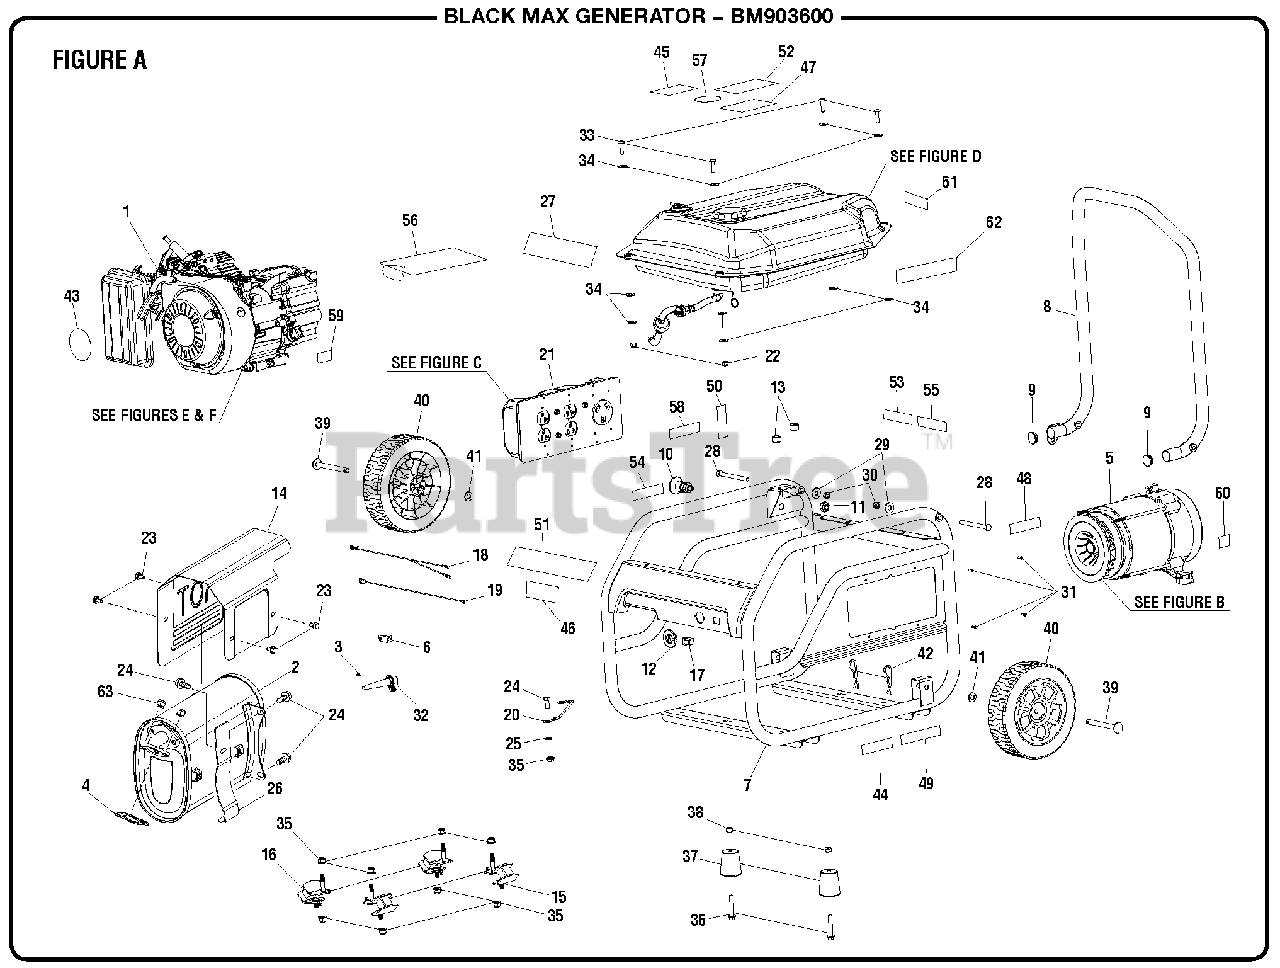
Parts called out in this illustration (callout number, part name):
3	Spark Arrestor Set Screw
4	Exhaust Gasket
5	Generator Head Assembly
6	Ground Lug
7	Frame Assembly
8	Handle Assembly
9	Cap (25 mm)
10	Handle Release Pin
11	Lock Nut (1/2-20)
12	Fuel Valve Bezel
13	Rubber Bumper
14	Heat Shield
15	Isolator (Left)
16	Isolator (Right)
17	Momentary Switch
18	Wire Assembly (Black)
19	Wire Assembly (Green)
20	Ground Wire Assembly
21	Control Panel Assembly
22	Lock Nut (M6)
23	Bolt (M8 x 10 mm, Hex Flange Hd.)
24	Bolt (M8 x 16 mm, Hex Flange Hd.)
25	Star Washer (M8)
26	Muffler Bracket
27	Performance Label
28	Handle Pivot Pin
29	Washer (5/16 in.)
30	Lock Nut (5/16-18)
31	Screw (#6-20 x .38 in., Type B)
32	Spark Arrestor
33	Bolt (M6 x 25 mm, Hex Hd.)
34	Washer (1/4 in., Type A)
35	Flange Lock Nut (M8)
36	Bolt (M8 x 45 mm, Hex Flange Hd.)
38	Lock Nut (M8)
41	Washer (M10)
42	Hitch Pin
43	Recoil Label
44	Inquiries Label
45	CPSC Label
46	Start Label
47	Danger Label
48	Fire Danger Label
49	Check Oil Label
50	Handle Release Label
51	Logo Label
52	E85 Label
53	Combustion Label (Eng/Sp)
54	Hot Surface Label
55	Ground Warning Label
56	Warning Hangtag
57	Fuel Stabilizer Label (Eng)
58	Fire Distance Label
59	Fuel Off Label
60	Ground Label
61	Fuel Stabilizer Label (Sp)
62	Logo Label
63	Lock Nut (M8)
